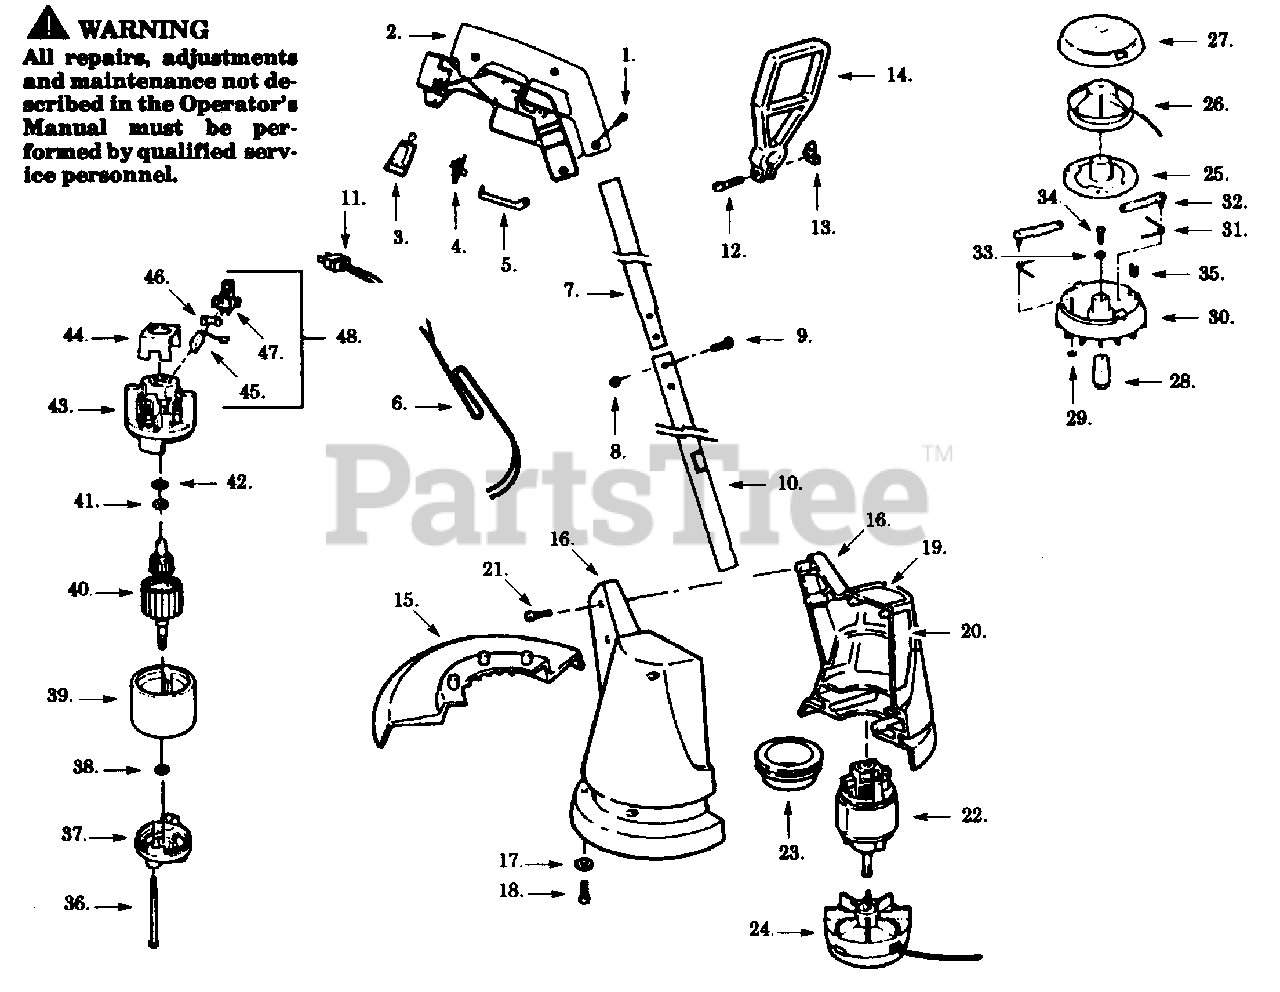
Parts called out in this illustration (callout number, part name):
2	Handle Set
3	Cord Retainer
4	On/Off Switch
5	Trigger Switch
6	Harness Ass'y.
7	Upper Tube
8	Nut
10	Lower Tube w/ Decal
11	Plug Ass'y.
13	Wing Nut
14	Assist Handle
15	Guard & Blade Assy.
16	Housing Set
19	Housing Label (Not a serviceable part)
20	Hsg. Front Label (Not a serviceable part)
22	Motor Ass'y.
23	Air Baffle
24	Cutting Head Ass'y.
26	Spool & Line
28	Drive Adapter
29	Push Nut
30	Housing Head
35	Line Shield
37	Endbell Ass'y. Drive
39	Field Ass'y.
40	Armature Ass'y.
43	Endbell Ass'y. Brush
44	Insulator
45	Carbon Brush
46	Brush Spring
47	Brush Holder
48	Brush Kit
